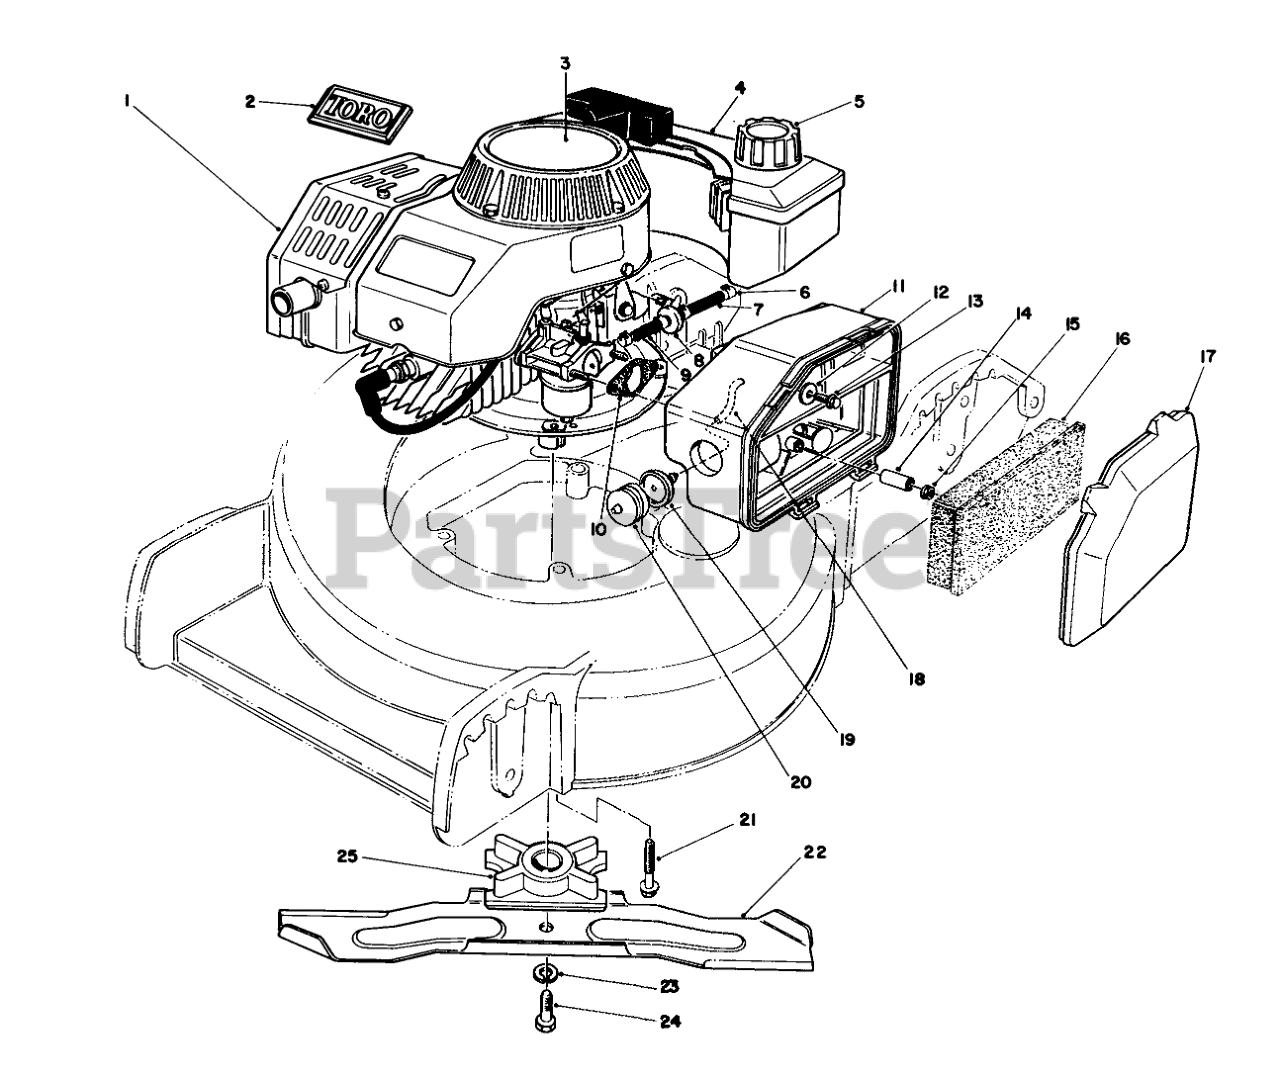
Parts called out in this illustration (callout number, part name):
1	Engine
2	TORO LOGO PLT
3	DECAL- 2 CYC RECOIL
4	Gas Tank Assembly
5	GAS CAP ASM
6	CLAMP-FUEL LINE
7	HOSE-FUEL
8	FILTER-FUEL
9	HOSE-FUEL
10	GASKET-AIR CLEANER
11	BODY-AIR CLEANER
12	WASHER-FLAT
13	SCREW-HH
14	HYDRAULIC TUBE
16	ELEMENT-AIR CLEANER
17	COVER-AIR CLEANER
18	HOSE-PRIMER
19	BODY-PRIMER
20	Bulb Primer
21	Bolt-Engine
22	Blade
23	WASHER-LOCK
24	SCREW-HH
25	BLADE RETAINER
